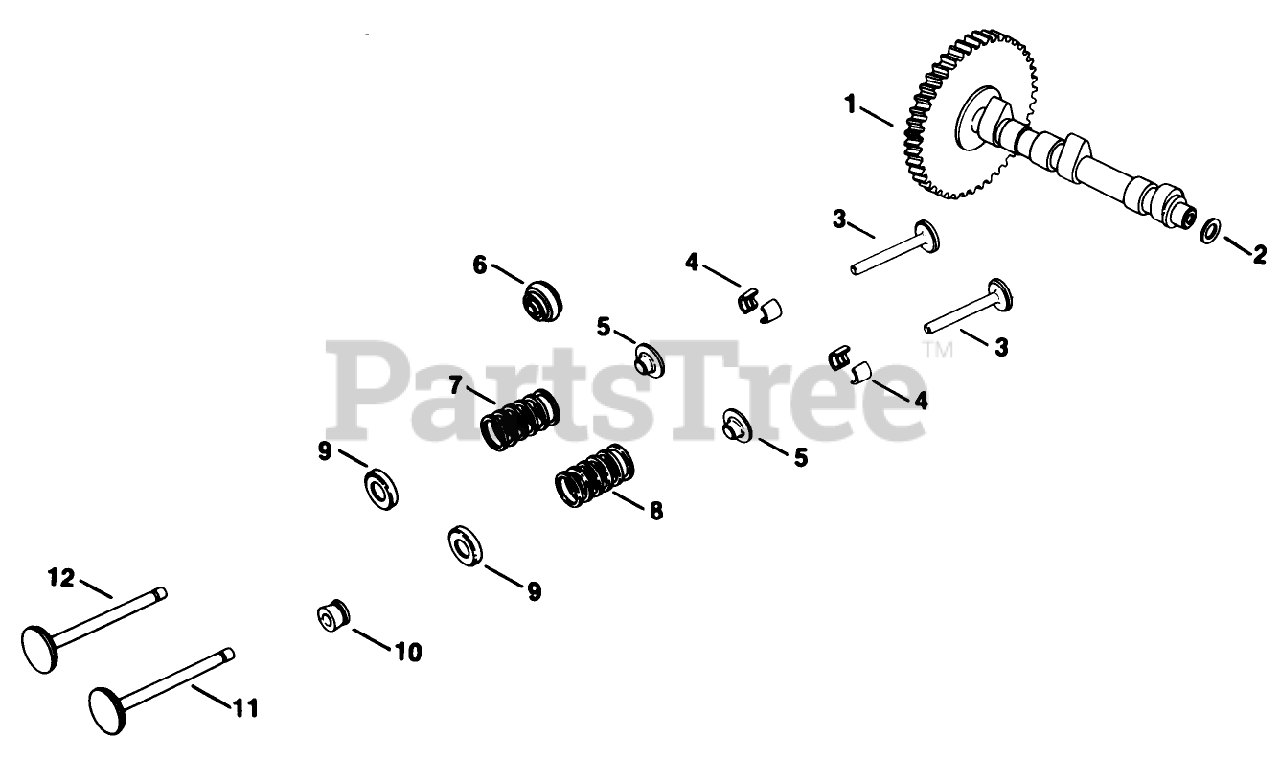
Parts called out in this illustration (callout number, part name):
1	Camshaft
2	Spacer-Camshaft
3	Tappet
4	Kit-Retainer
5	Retainer-Spring
6	Rotator
7	Spring Exhaust Valve
8	Spring, Valve
9	Retainer-Spring
10	Seal-Valve Stem
11	Valve-Intake
12	Valve-Exhaust
